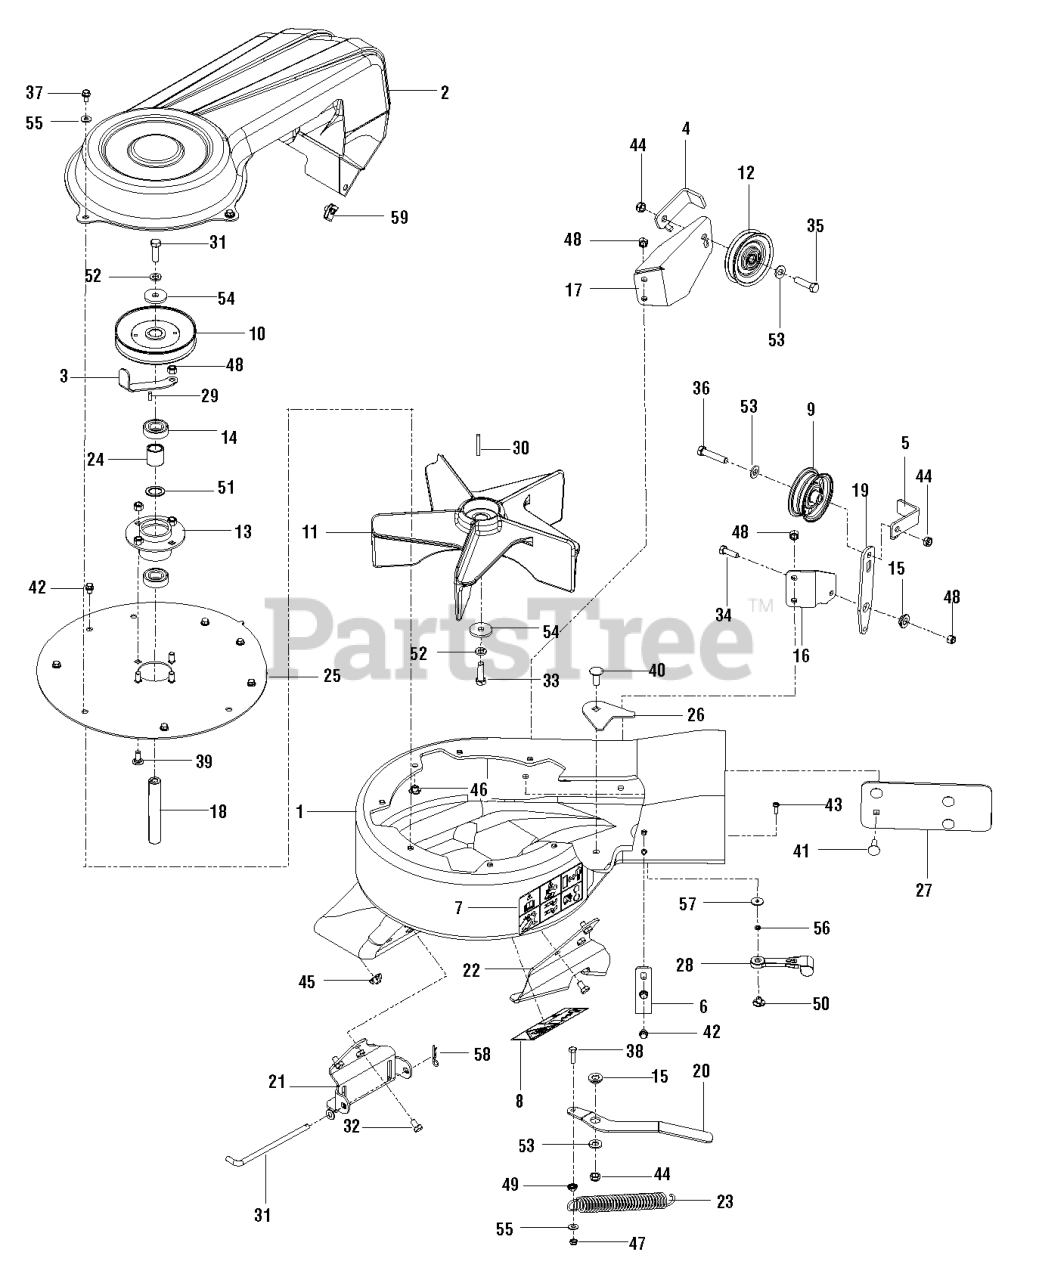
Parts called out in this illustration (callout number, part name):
1	BLOWER.HOUSING.W/DECALS.COLLEC
2	COVER, BELT
3	KEEPER, BELT, OUTER
4	KEEPER FLAT LOWER BLACK
5	KEEPER FLAT UPPER BLK
7	DECAL, EURO WARNING
8	EURO DECAL, IMPELLER
9	PULLEY, IDLER, BACKSIDE
11	IMPELLER.COLLECTION.BLOWER.BLA
13	HUB, BEARING
16	MOUNT.IDLER.UPPER
17	MOUNT IDLER LOWER
18	SHAFT, IMPELLER
20	ARM, TENSION
21	BRKT, MT, FRONT
22	BRKT, MT, REAR
25	PLATE, OUTER
26	PLATE, BACKING
27	PLATE.BACKING.BLACK
28	HOOD LATCH
29	KEY, 3/16 X 1/2
30	KEY-SQ. 3/16 X 1 1/2
31	PIN
32	HCS 5/16-18 X 1/2 GR 5 ZD
33	BOLT, HEX 3/8-24 X 1.25 GR 8
34	HCS 5/16C X 1
35	HCS 3/8C X 1 1/2
36	BOLT, HCS 3/8-16X1-3/4
37	BOLT 1/4-20 X 1/2 HWST
38	HCS 1/4-20X7/8 GR5
39	BOLT 5/16C X 3/4" CARRIAGE
40	RHSNB 3/8C X 1
41	RHSNB 5/16C X 1
42	HWST 1/4C X 3/8
43	SCREW #10-24 X 5/8
44	NUT HEX 3/8-16 NYLON, THIN
45	NUT 5/16-18 TEE
46	NUT 1/4-20 TEE
47	JAM NUT 1/4C (2 2 PW01)
48	NUT 5/16 NYLOC
49	NUT 1/4-20 HEX FLG LK ZD
50	NUT 10-24 WELD PLATED
51	WASHER .787 X 1.125 X .06
52	BOLT 5/16C X 3/4" CARRIAGE
53	WASHER 3/8 SAE FLAT
54	WASHER, HARDENED
55	WASHER 1/4 SAE
56	WASHER - 3/16 LOCK ZD
58	HAIRPIN #2
59	U-CLIP 5/16-18 NUT RETAINER
